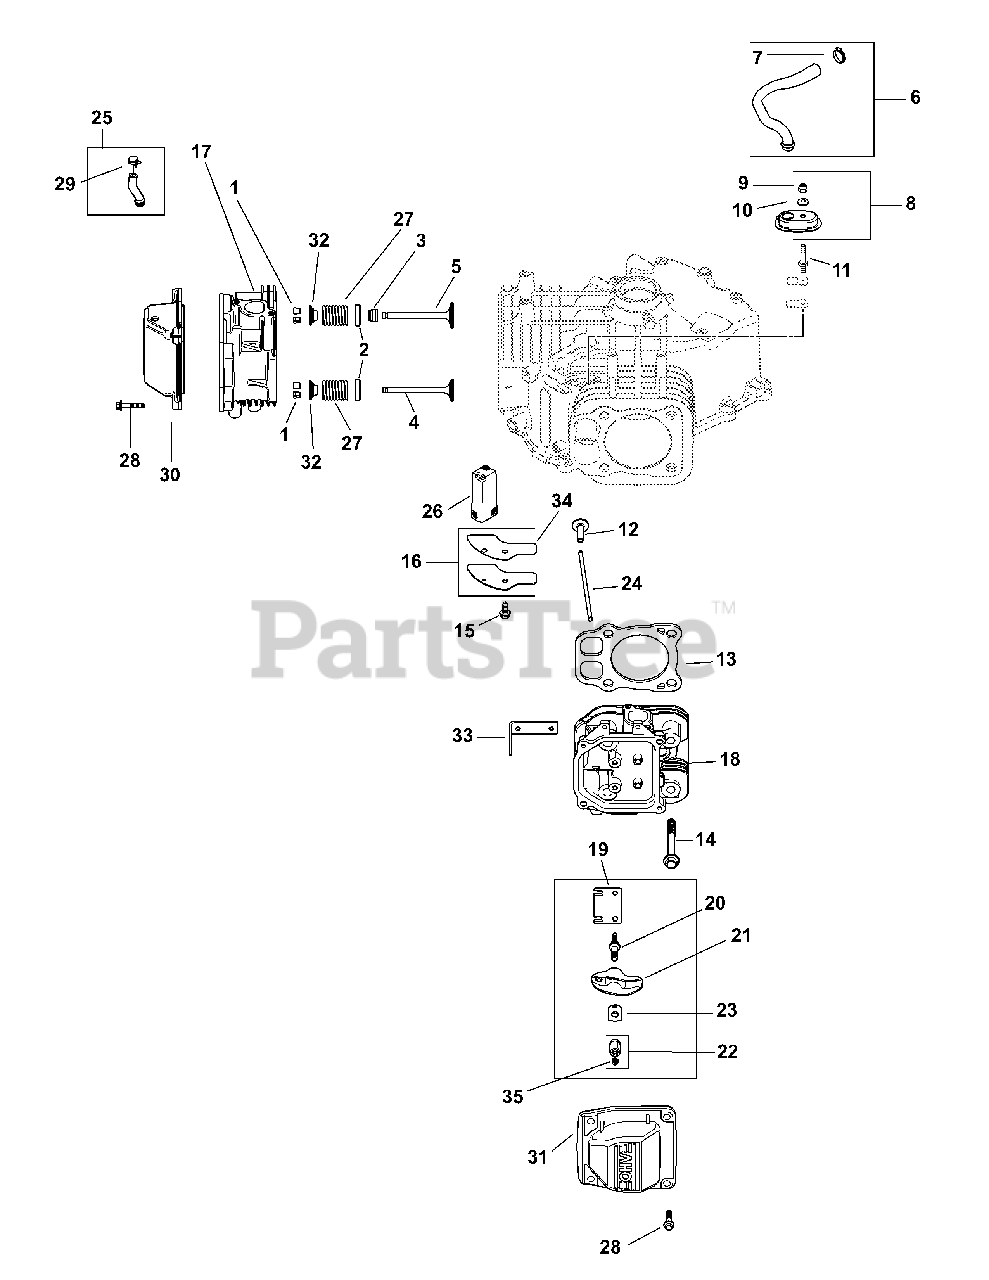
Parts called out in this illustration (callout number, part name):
1	Retainer Kit
2	Spring Retainer
3	Valve Stem Seal
4	Exhaust Valve (STD)
5	Intake Valve (STD)
6	Breather Hose Kit (Inc. #7)
7	Hose Clamp, 1/2
8	Breather Housing Kit (Inc. #9 & 10)
9	Lock Nut, M5 x .8
10	Sealing Washer
11	Breather Cover Stud
13	Cylinder Head Gasket Kit
14	Flange Screw, M10 x 1.5 x 90
15	Flange Screw, M6 x 1.0 x 16
16	Breather Cover Kit
17	#1 Cylinder Head Assembly Kit
18	#2 Cylinder Head Assembly Kit
22	Hex Nut Assembly
23	Rocker Arm Pivot
25	Fuel Pump Hose w/ Clamp Kit
26	Breather Filter
27	Valve Spring
28	Pan Head Screw
30	Rocker Stamped Steel Cover
31	Rocker Stamped Steel Cover
32	Valve Spring Cap
33	Lifting Strap
34	Breather Cover
